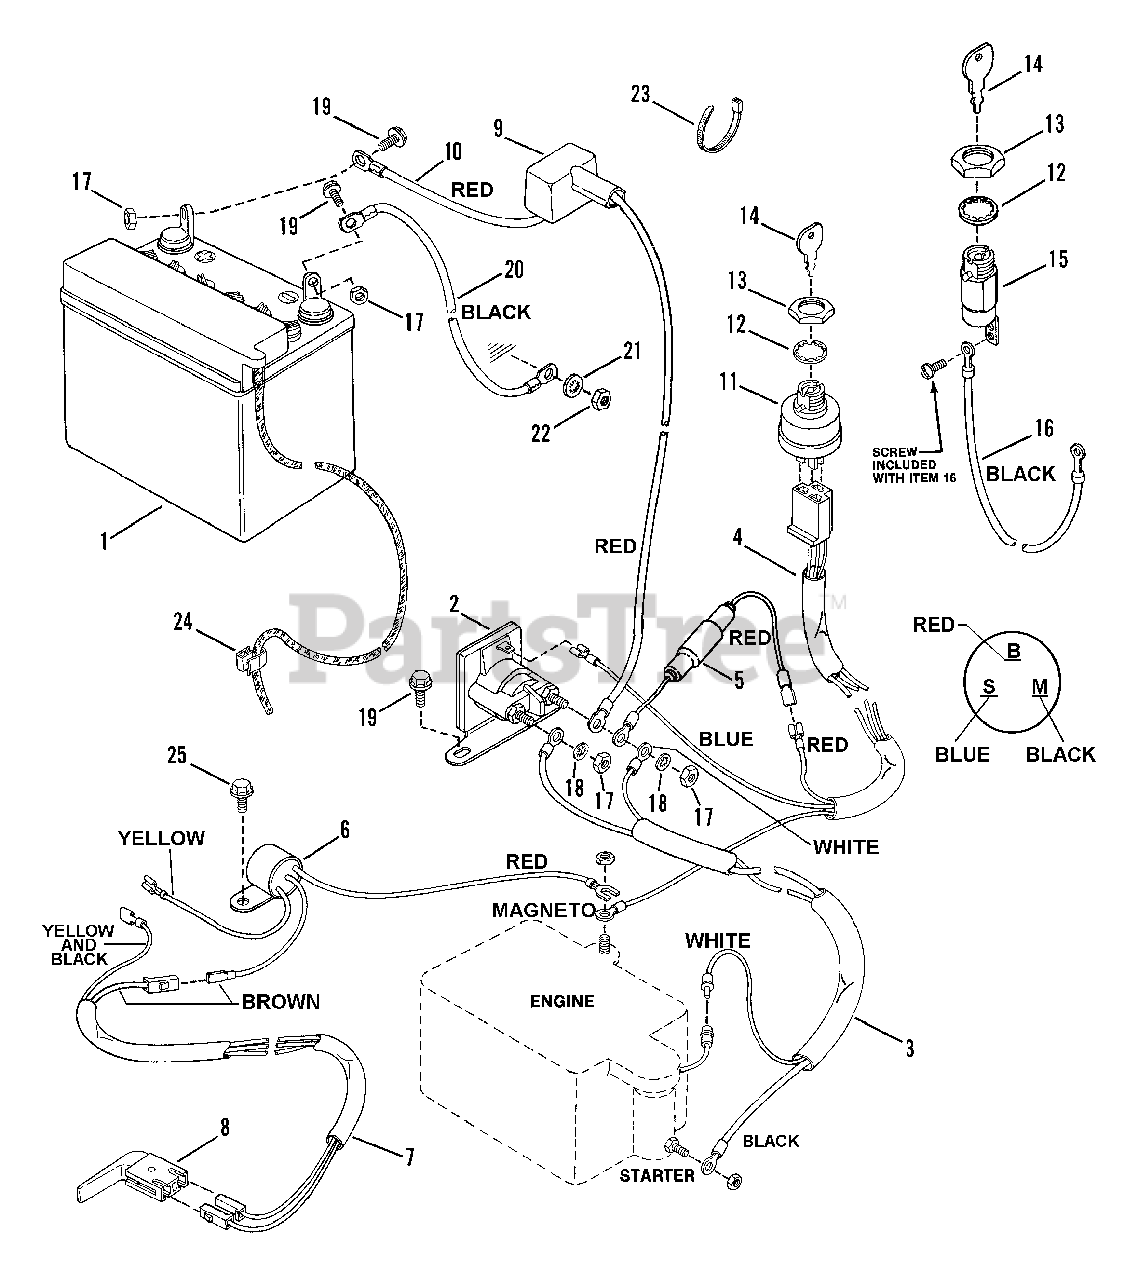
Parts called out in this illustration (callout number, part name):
1	KIT, 12V Dry Charge Battery
2	SOLENOID
3	HARNESS, Starter Wiring
4	HARNESS, Ignition Wiring
5	HOLDER, Fuse
6	INTERLOCK Kit
7	HARNESS, Deck Interlock Wiring
8	SWITCH, Deck Interlock
9	COVER, Battery Cable
10	CABLE, Positive (Red)
11	SWITCH, Ignition
12	WASHER, 5/8 Internal Tooth Lock
13	NUT, 5/8-32 Hex
14	KEY, Switch (With Cover)
15	SWITCH, Ignition
16	WIRE, Ground
17	NUT, 1/4-20 Hex
18	WASHER, 1/4 Internal Tooth Lock
19	SCREW, 1/4-20x5/8" Hex Head Cap
20	CABLE, Negative
21	WASHER, 5/16 Internal Tooth Lock
22	NUT, 5/16-18 Hex
23	CABLE-TIE
24	CLIP, Battery Hose
25	SCREW, 1/4-20x1/2" Hex Head Self-Tapping
